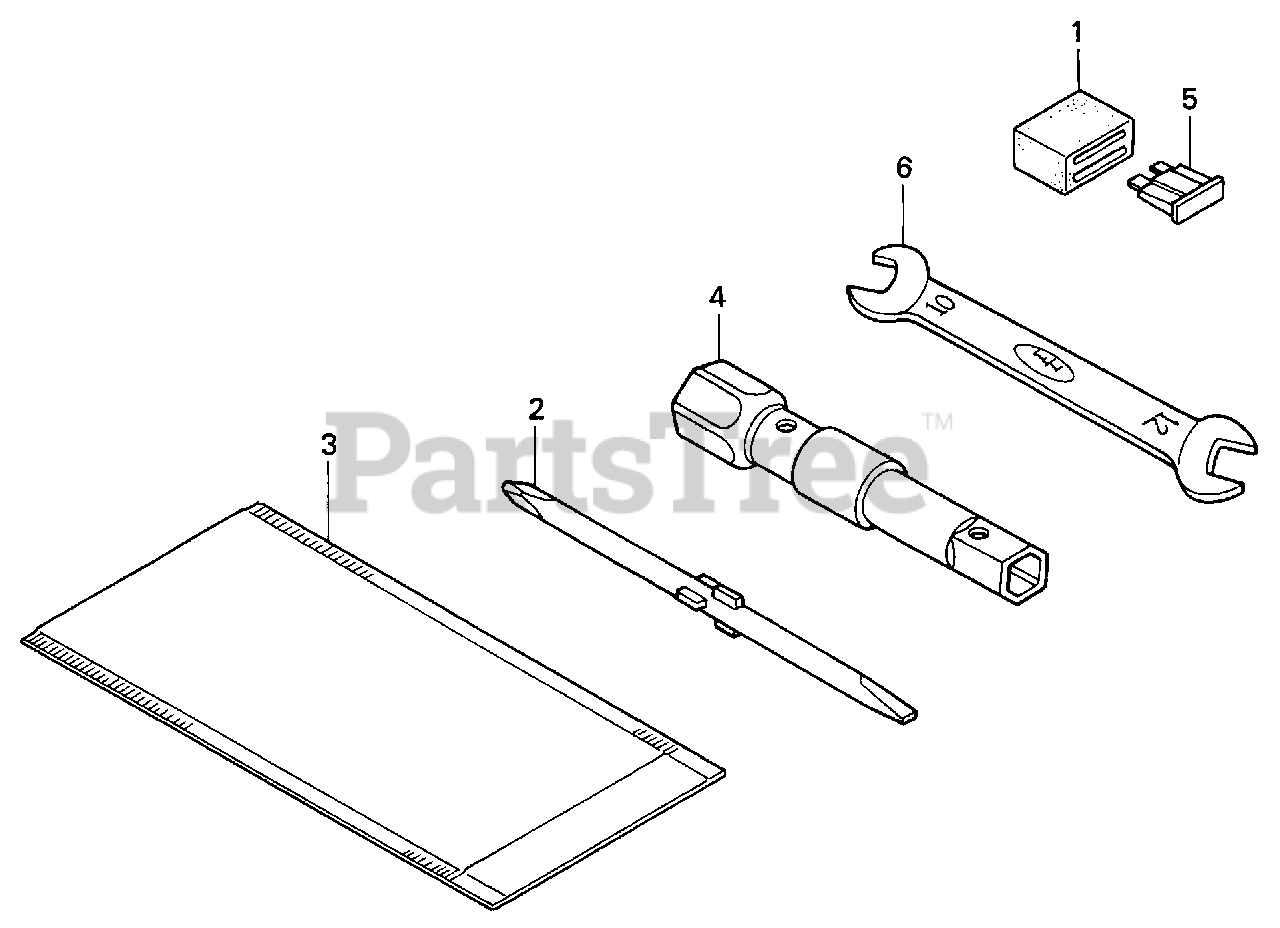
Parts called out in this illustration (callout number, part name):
2	DRIVER (NOT AVAILABLE)
3	BAG, OWNER'S MANUAL
4	WRENCH, BOX (P21X12)
